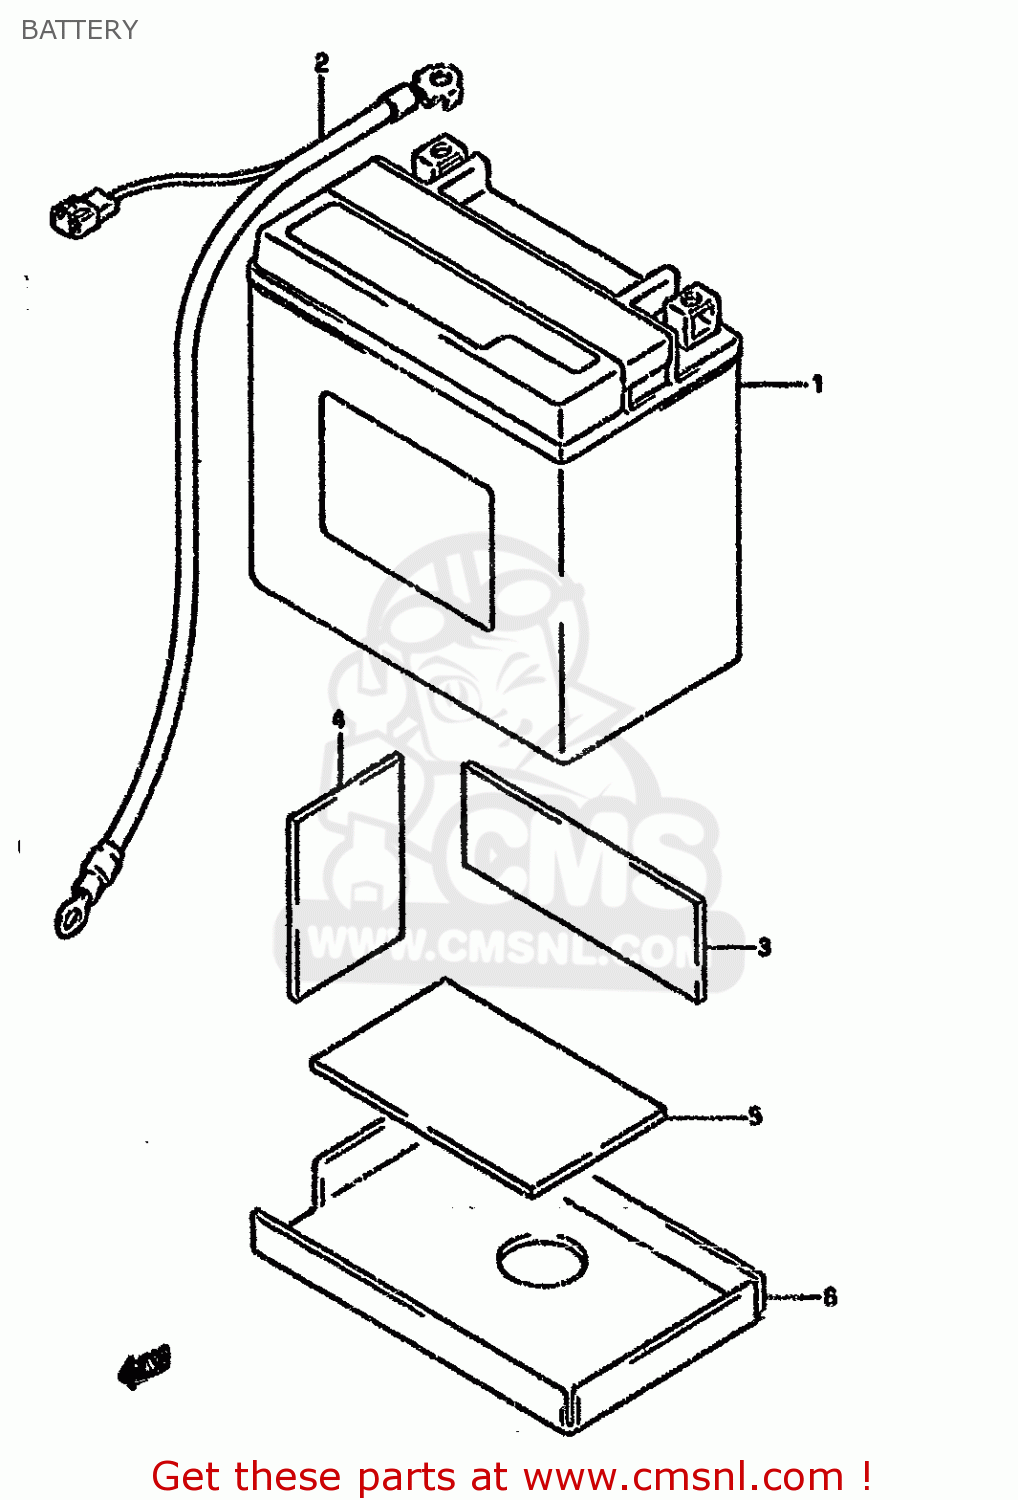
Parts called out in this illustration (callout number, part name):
1	BATTERY ASSY (12V) YTX14-BS
2	LEAD WIRE,BATTERY (-)
3	PROTECTOR,20X9
4	PROTECTOR,BATTERY
5	PROTECTOR(170X95X3.0)
6	PROTECTOR,BATTERY
